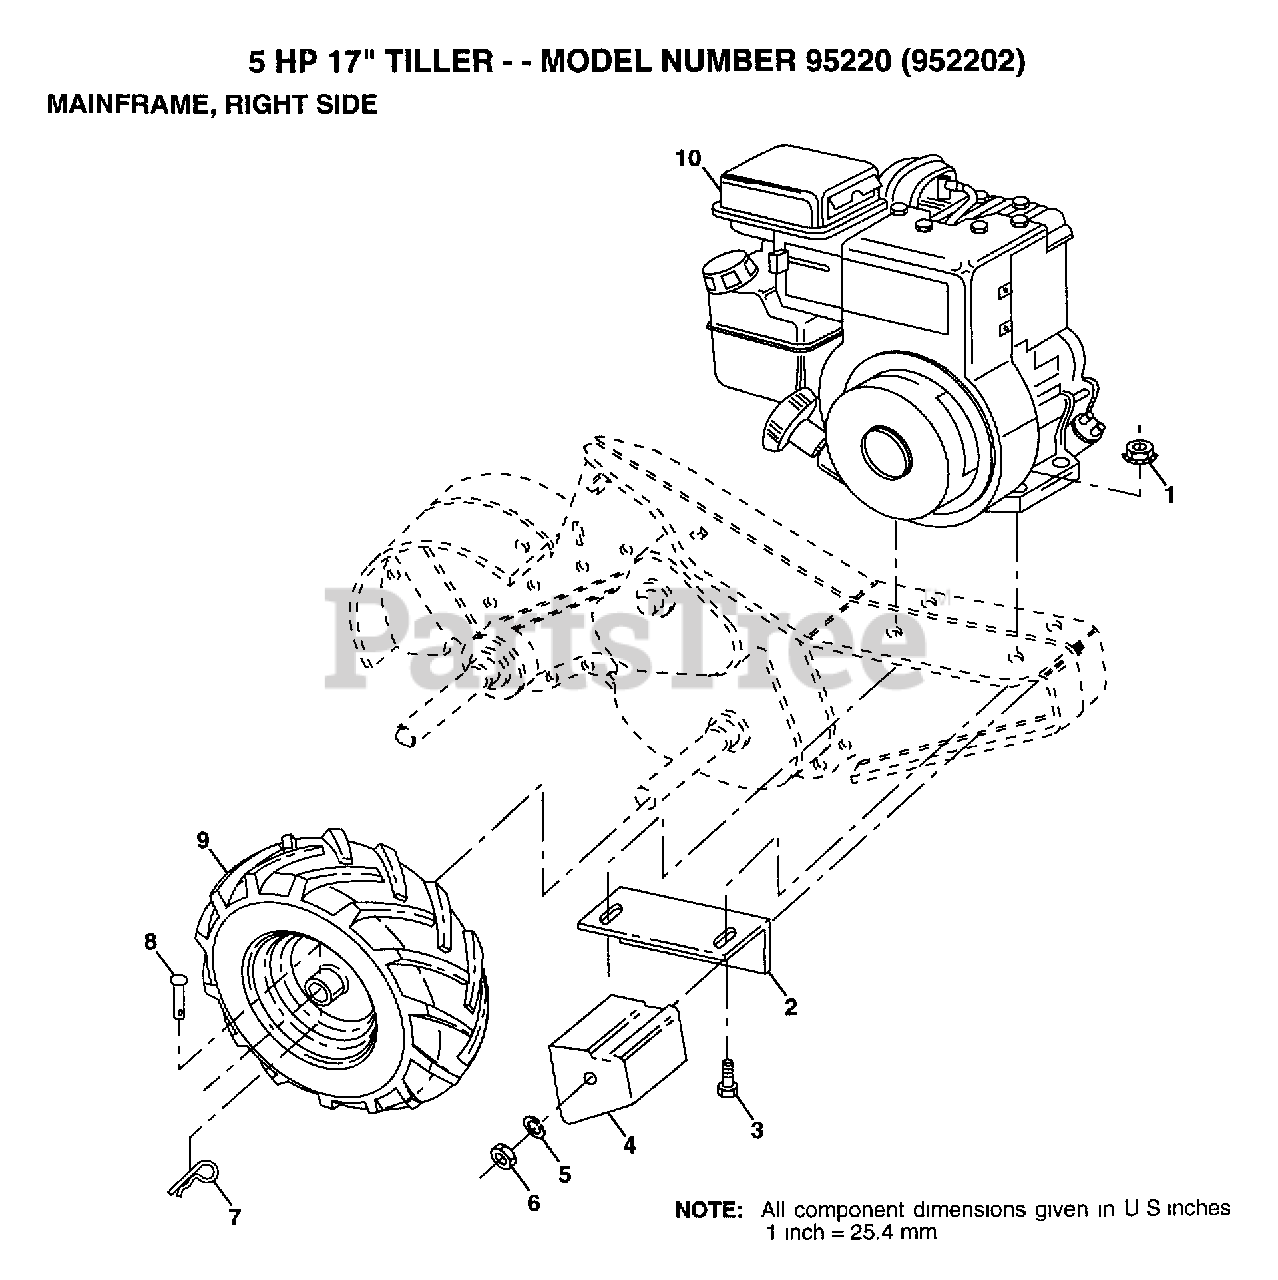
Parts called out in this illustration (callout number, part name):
2	BRACKET RH CRT
3	BOLT.HEX.5/16-1.5
4	COUNTERWEIGHT CRT
5	LOCKWASHER
6	NUT.HEX.3/8-16UNC
7	RETAINER M
8	RIVET.DRILL.1.75
9	TIRE.CHV.13X5.0-6
